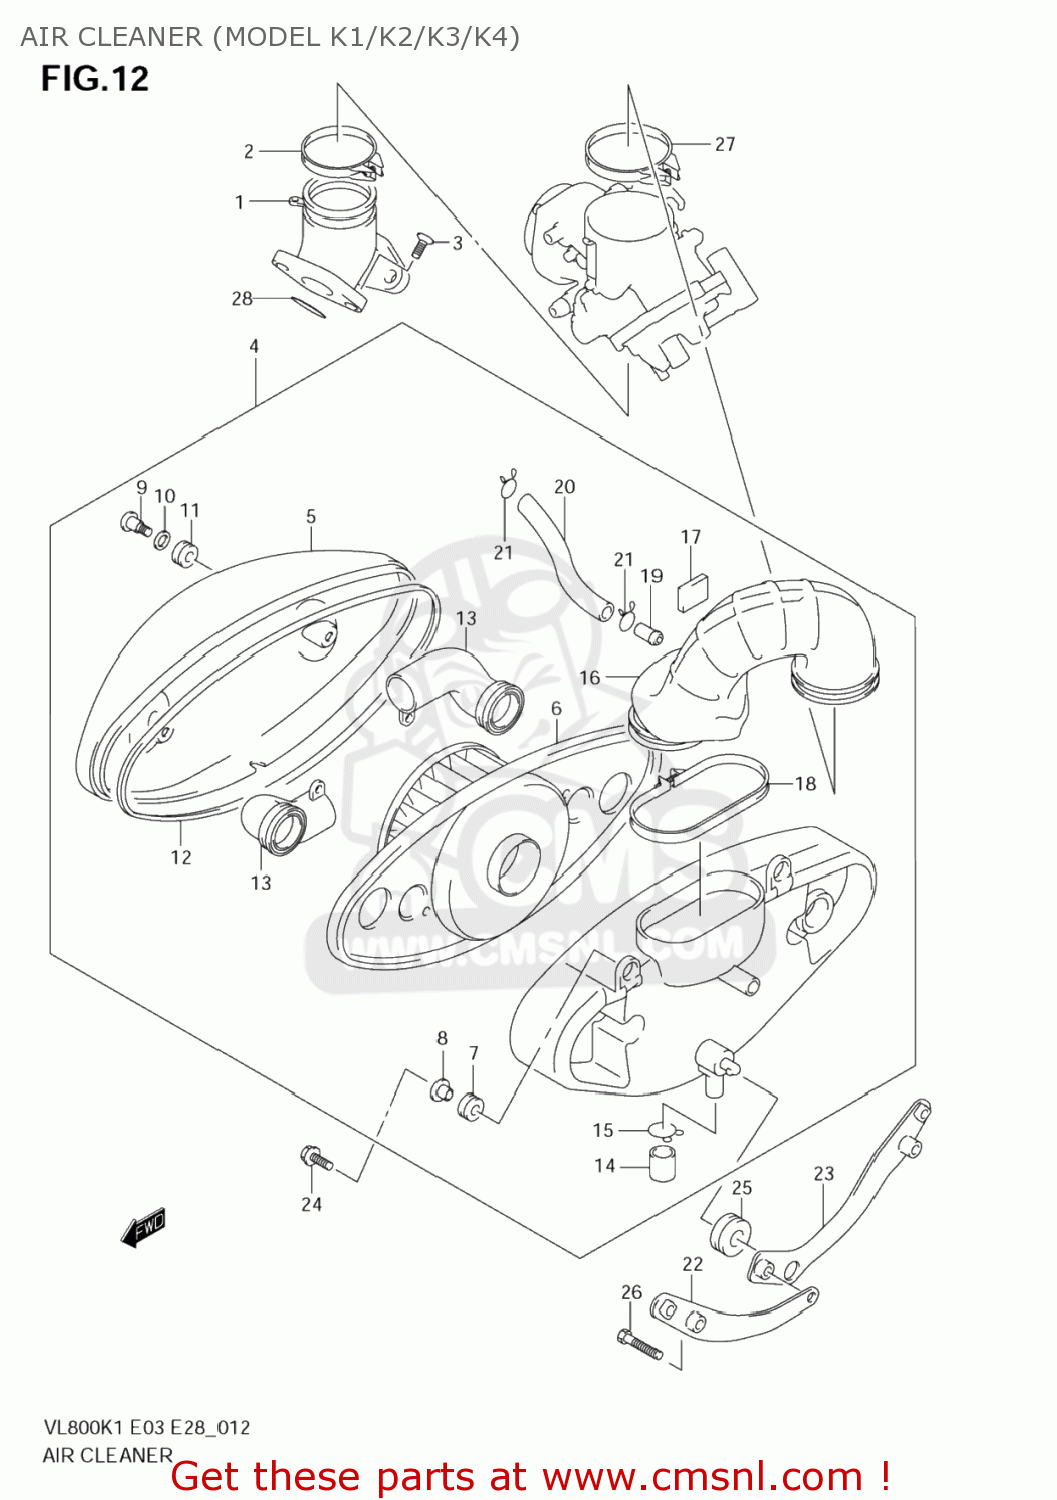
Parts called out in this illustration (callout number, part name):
1	PIPE ASSY,INTAKE
2	CLAMP
3	BOLT(6X20.5)
4	CLEANER ASSY,AIR
5	CAP,AIR CLEANER
6	FILTER ASSY
7	CUSHION
8	COLLAR,CLEANER CASE
9	SCREW(6X20)
10	WASHER
11	CUSHION
12	GASKET (NAS)
13	TUBE,INLET
14	PLUG
15	CLIP
16	TUBE,OUTLET
17	CUSHION
18	CLAMP
19	PIPE A,TUBE OUTLET
20	TUBE,BREATHER
21	CLIP
22	BRACKET,AIR CLEANER FR
23	BRACKET,AIR CLEANER RR
24	SCREW(6X20)
25	CUSHION
26	BOLT
27	CLAMP
28	O RING(D:1.9,ID:40.7)
